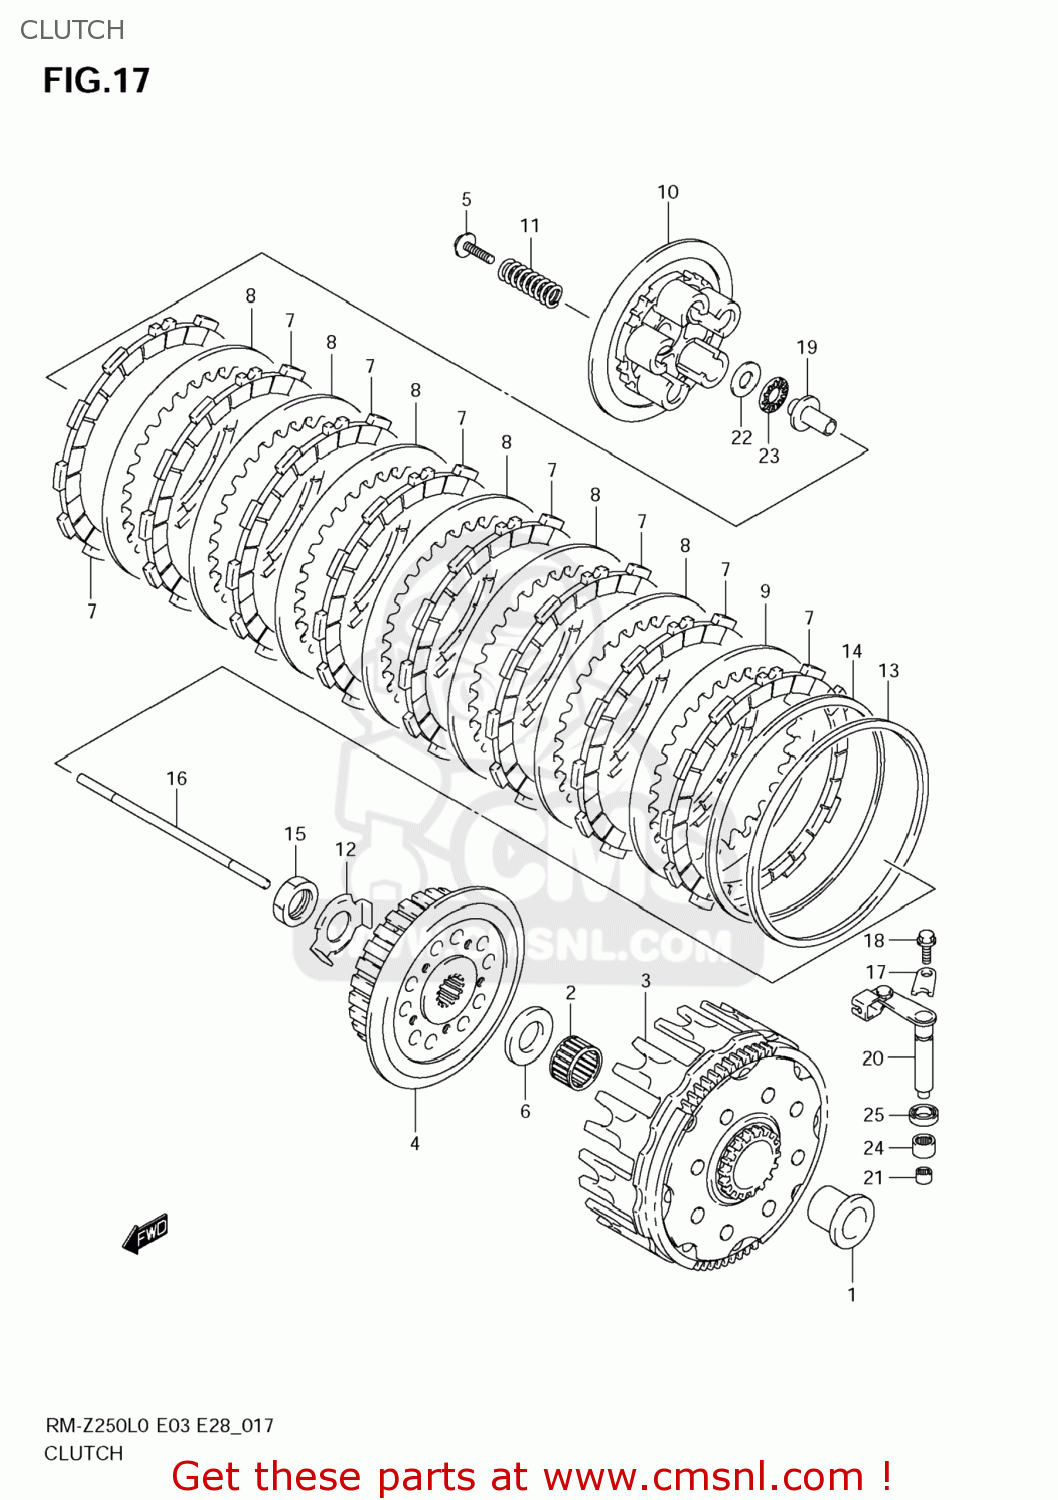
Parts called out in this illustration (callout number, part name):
1	SPACER,PRIMARY DRIVEN GEAR
2	BEARING(27X32X21.8)
3	GEAR ASSY,PRI DRIVEN
4	HUB,CLUTCH SLEEVE
5	BOLT,CLUTCH SPRING
6	WASHER(22X45X3)
7	PLATE,CLUTCH DRIVE (NAS)
8	PLATE,CLUTCH DRIVEN (NAS)
9	PLATE,CLUTCH DRIVEN (NAS)
10	DISC,CLUTCH PRESSURE
11	SPRING,CLUTCH
12	WASHER,CLUTCH SLEEVE HUB LOCK
13	SEAT,CLUTCH PLATE WAVE WASHER
14	WASHER,CLUTCH PLATE
15	NUT
16	ROD,CLUTCH PUSH
17	RETAINER,CL RELEASE CAMSHAFT
18	BOLT(6X12)
19	PIECE,CLUTCH PUSH
20	CAMSHAFT,CLUTCH RELEASE
21	BEARING,CLUTCH RELEASE(7X11X9)
22	SHIM(12X26X0.8)
23	BEARING(12X26X2)
24	BEARING(10X14X10)
25	SEAL,OIL(10X17X5)
